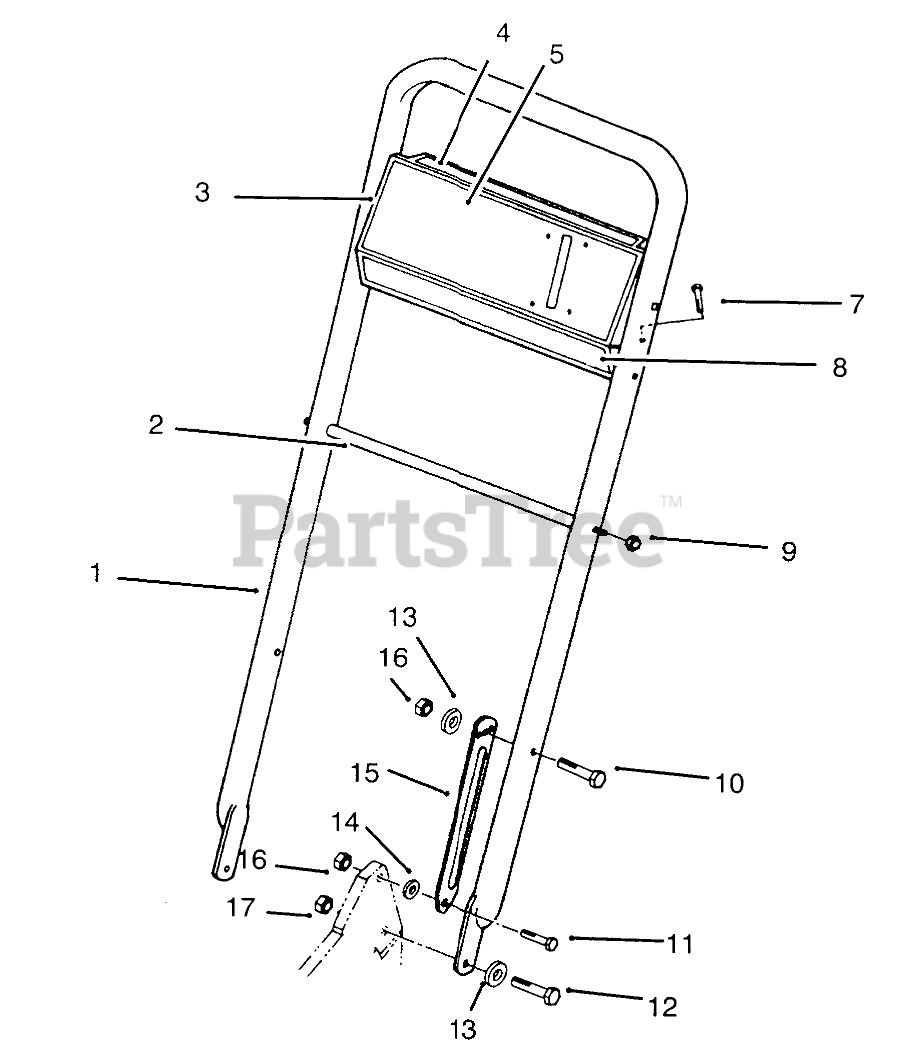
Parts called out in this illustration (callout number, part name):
1	Handle
2	ROD-SUPPORT, BAG
3	Panel-Control (Incl. Ref. #4,5,& 8)
4	DECAL-PANEL, REAR
5	DECAL - PANEL
7	SCREW-HWHTF
8	DECAL-PANEL, PROLINE
9	NUT-CAP
10	SCREW-HH
11	SCREW-SHOULDER
12	SCREW-HH
13	WASHER-BELLEVILLE
14	SPACER
15	Latch-Handle
16	NUT-LOCK, NI
17	NUT-LOCK, NI
